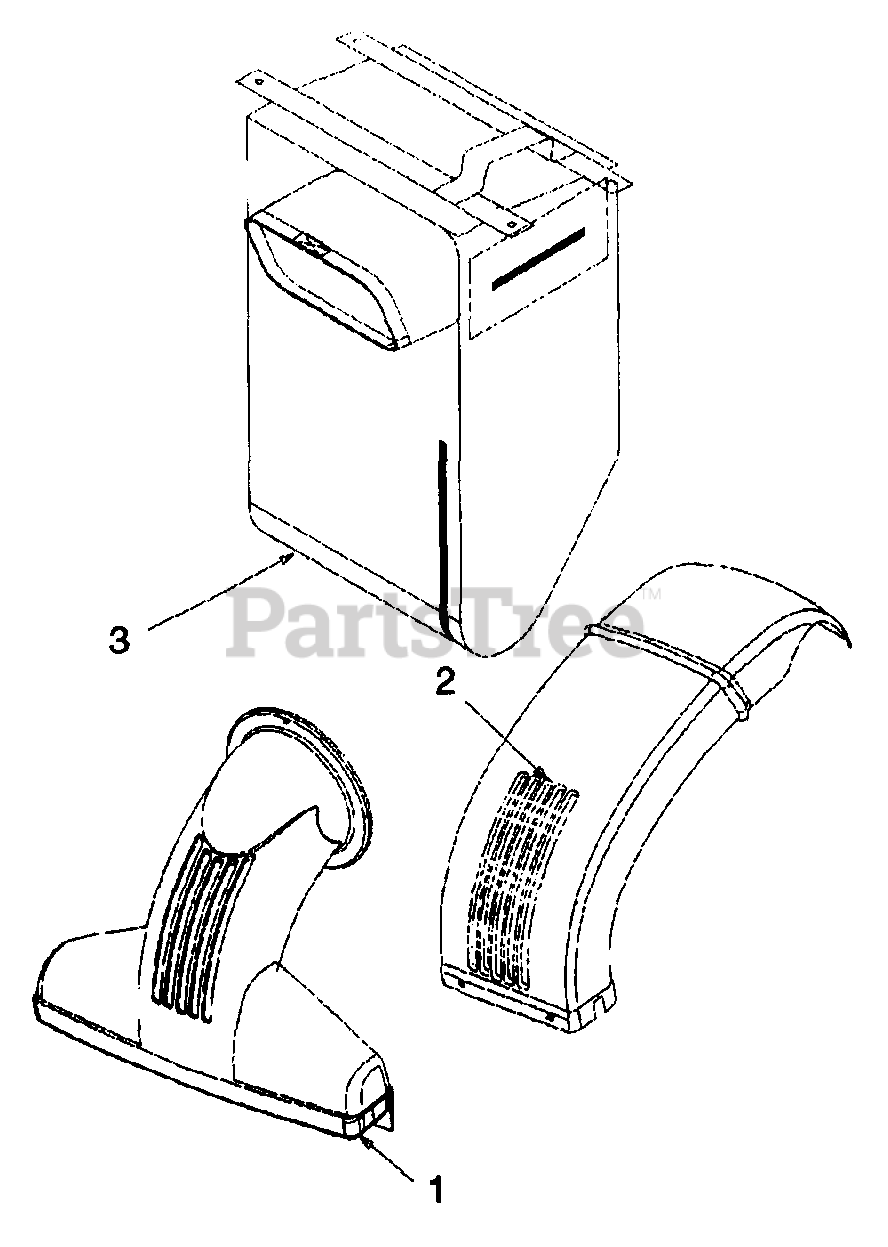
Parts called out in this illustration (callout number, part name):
1	Nozzle Assembly, Vacuum
2	Chute, Discharge
3	Bag, Vacuum
